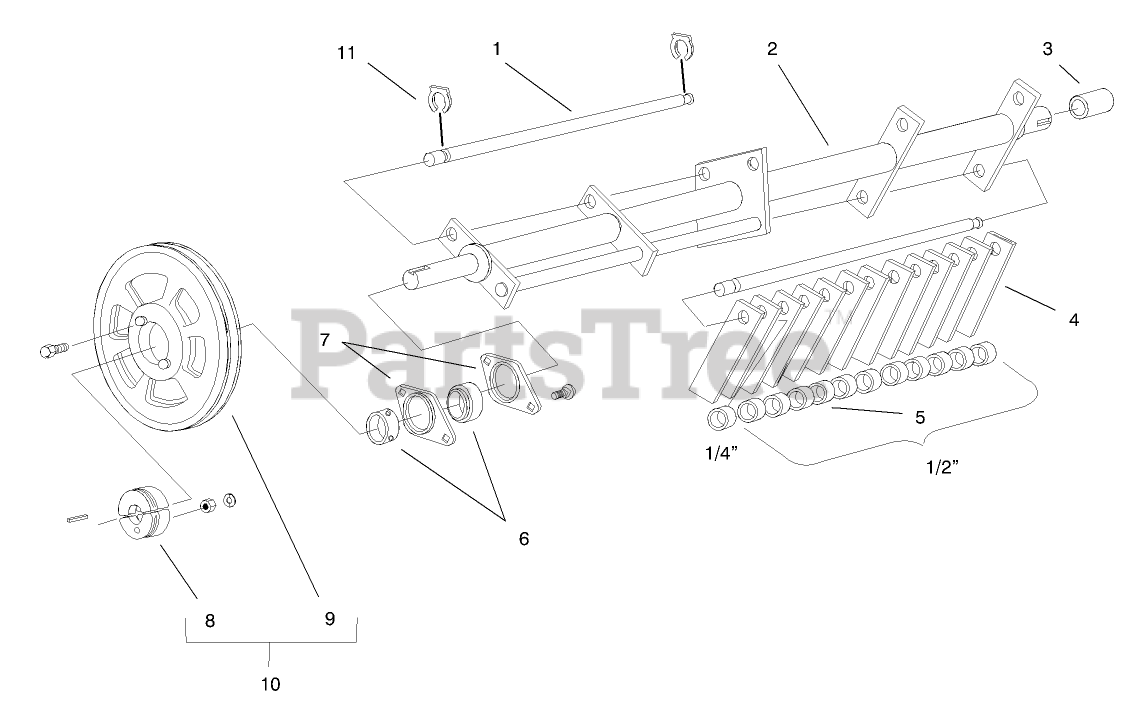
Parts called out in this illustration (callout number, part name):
1	Shaft Kit (Incl. Ref. #11)
2	ROTOR
4	BLADE SET
5	SPACER SET
6	BEARING
7	KIT - STAMPING
8	BUSHING
9	V-PULLEY
10	V-PULLEY
11	C CLIP
